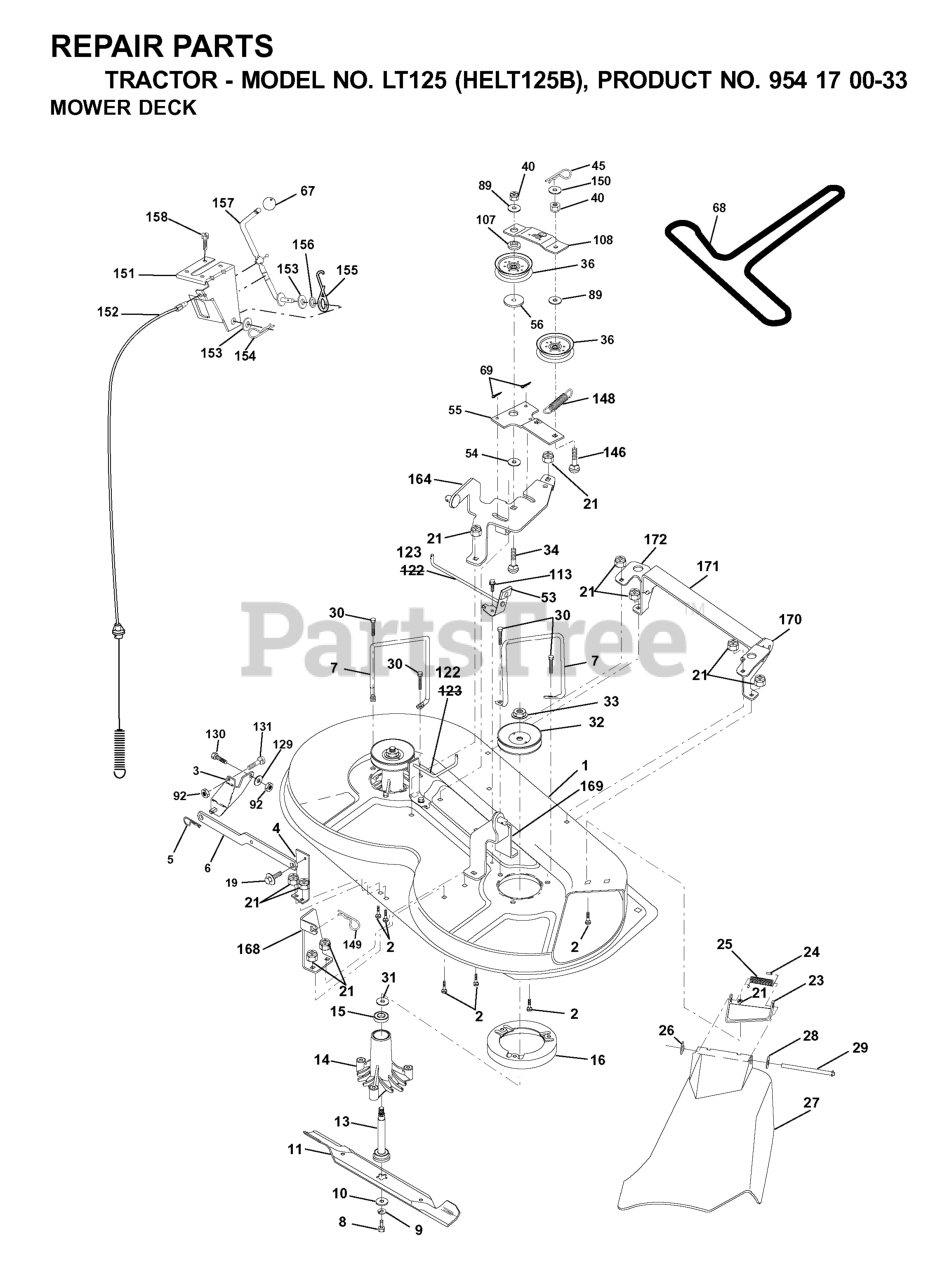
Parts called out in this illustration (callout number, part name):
2	RP BOLT 5/16-18 X3/4 ZN/YEL GR
3	BRKT ASM SWAY BAR
5	RETAINER-SPRNG RB
6	REAR SUSP ARM
8	BLADE BOLT
9	LOCKWASHER
10	WASHER.BLADE
11	BLADE, HI-LIFT 36" PREMIUM
13	SHAFT ASM VENT
14	HOUSING.MANDREL.VENTED (MACHD)
16	STRIPPER.MANDREL.ROUND.BLACK
19	BOLT SHD 5/16-18
21	LOCKNUT
23	BRACKET ASM DEFLECTOR
24	CAP-SLEEVE LT
25	SPRING TORSION
26	NUT PUSH M
27	CONSOLE.STLT.5SP.BLK
28	Washer 11/32 x 5/8 x 16 Ga SD
29	HINGE ROD
30	SCREW THDROL ROLLING WASHER HD
31	WASHER
32	PULLEY, MANDREL
33	NUT
36	FLAT IDLER PULLEY
45	RETAINER M
53	BRAKE ASSEMBLY
54	HARDENED WASHER
56	SPACER.RETAINER.MOWER
67	KNOB T (3/8 HOLE)
69	COTTER PIN
89	WASHER GT
92	NUT
107	SPACER.IDLER.ARM
108	STIFFENER.IDLER.ARM
113	Screw 5/16-18 x 1/2 Hex, Self Tapping 5/16-18 x 1/2
129	WASHER
131	BOLT D
146	BOLT, CARRIAGE IDLER
148	IDLER RETURN SPRING
149	SPRING.RETAINER.YELLOW.ZINC
151	BRACKET.CLUTCH.CABLE
153	WASHER FLAT 3/8"
154	SPRING RETAINER
155	SPRING RETENTION LEVER
156	SPACER.CLUTCH.CABLE
157	ROD CLUTCH CABLE 3/8"
158	SCREW LT
171	BRACE.SUPT.SUSP.FRT.CRD
